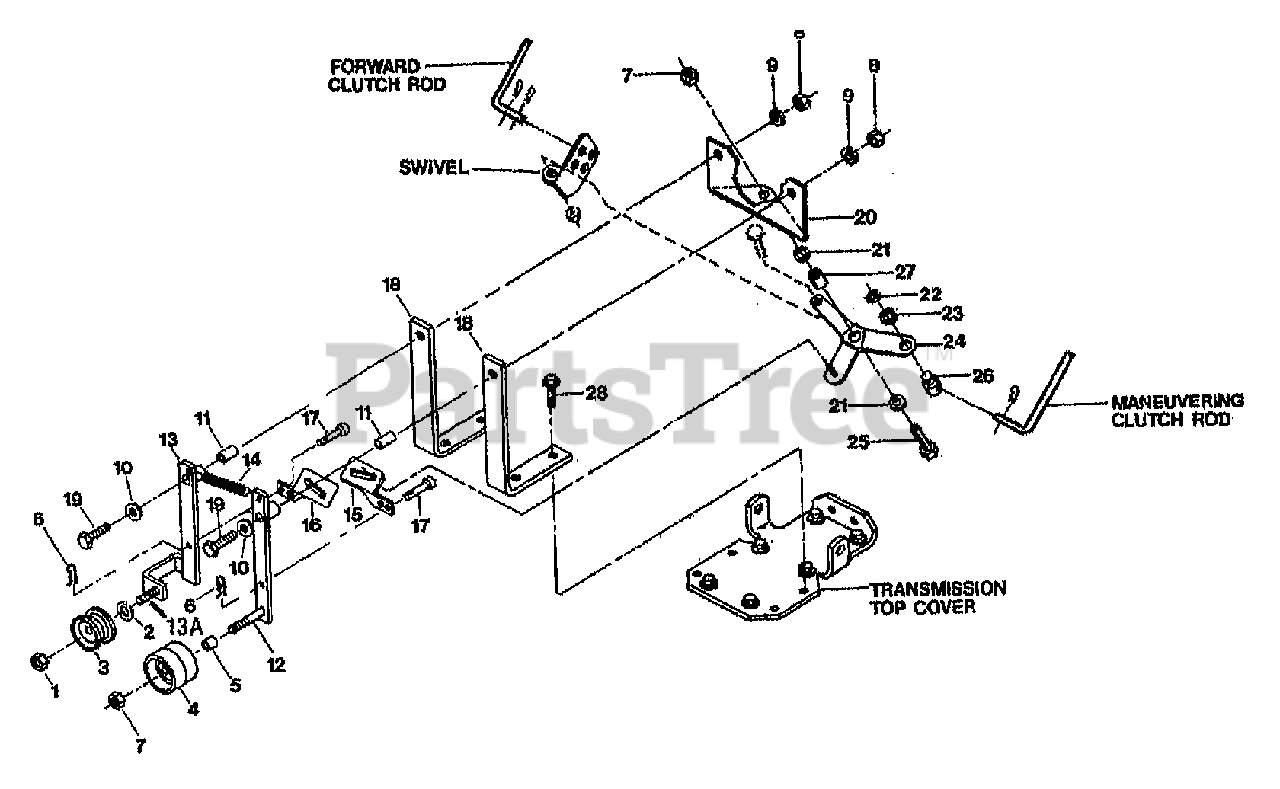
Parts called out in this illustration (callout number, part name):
1	NUT-LOCK 3/8-16 NYLON ZP
2	BUSHING-.54X.38X.08
3	IDLER-REV
3	PULLEY-IDLER REVERSE
4	PULLEY-IDLER FORWARD
5	SPACER-IDLER FWD
6	PIN-CLIP .08
7	NUT-H/LK 3/8-16
8	NUT-HEX 5/16-18 ZP
9	WASHER-LK .312 ZP
10	WASHER-#.75X.32X.09 ZP
11	BUSHING-.438X.323X.712
12	ARM-IDLER FWD PNT
13	IDLER-REV
13	ARM-IDLER REV RED
13A	SCR-HH 3/8-16X1.25
14	SPRING-.436 X 3.25
15	LINK-FWD
17	PIN-CLEVIS .375X.719 ZP
18	MOUNT BAR-PNT (20691)
19	SCR-HH 5/16-18X2.25 G5ZP
20	SHIFT BASE-OPC PNT
21	SPACER-.88X.385X.09 ZP
22	RING-KLIP .500 ZINC
23	WASHER-#.88X.51X.063 ZP
24	BELLCRANK-OPC PNT
25	SCR-HH 3/8-16X1.25
26	PIVOT-ROD (FOR MANEUVERING CLUTCH LEVER)
27	BUSHING-.5X.38X.4
28	SCR-HFLK 5/16-18X1.00 ZP
